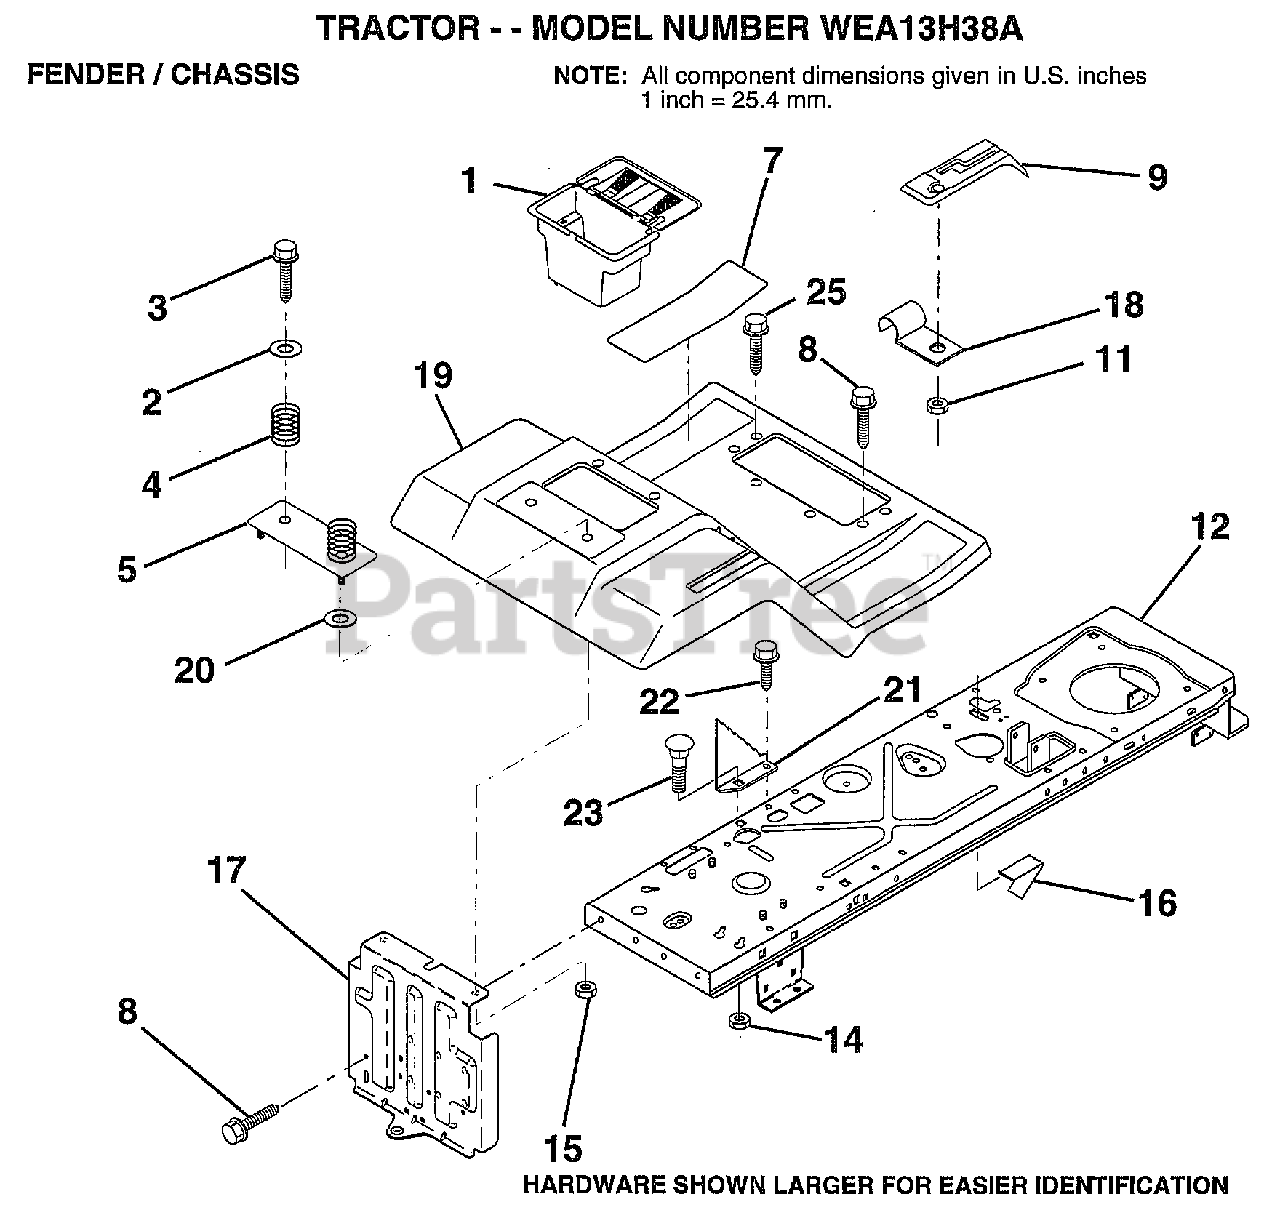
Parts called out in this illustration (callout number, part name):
1	"CASE,BATTERY.MECH"
2	WASHER
3	SCREW
4	SPRING COMPRESSIO
5	PLATE.FEND.LR.ASM
7	PAD FOOTREST
8	SCREW
9	CONSOLE.HYD.W/IGN
11	NUT
12	CHASSIS.WELD.ASM.
15	NUT HXKEP 1/4X20
17	DRAWBAR ASM LR
18	"CLIP,INSULATOR"
19	FENDER.FOOTREST
21	BRACKET STOP DEPT
22	SCREW LT
25	SCREW
